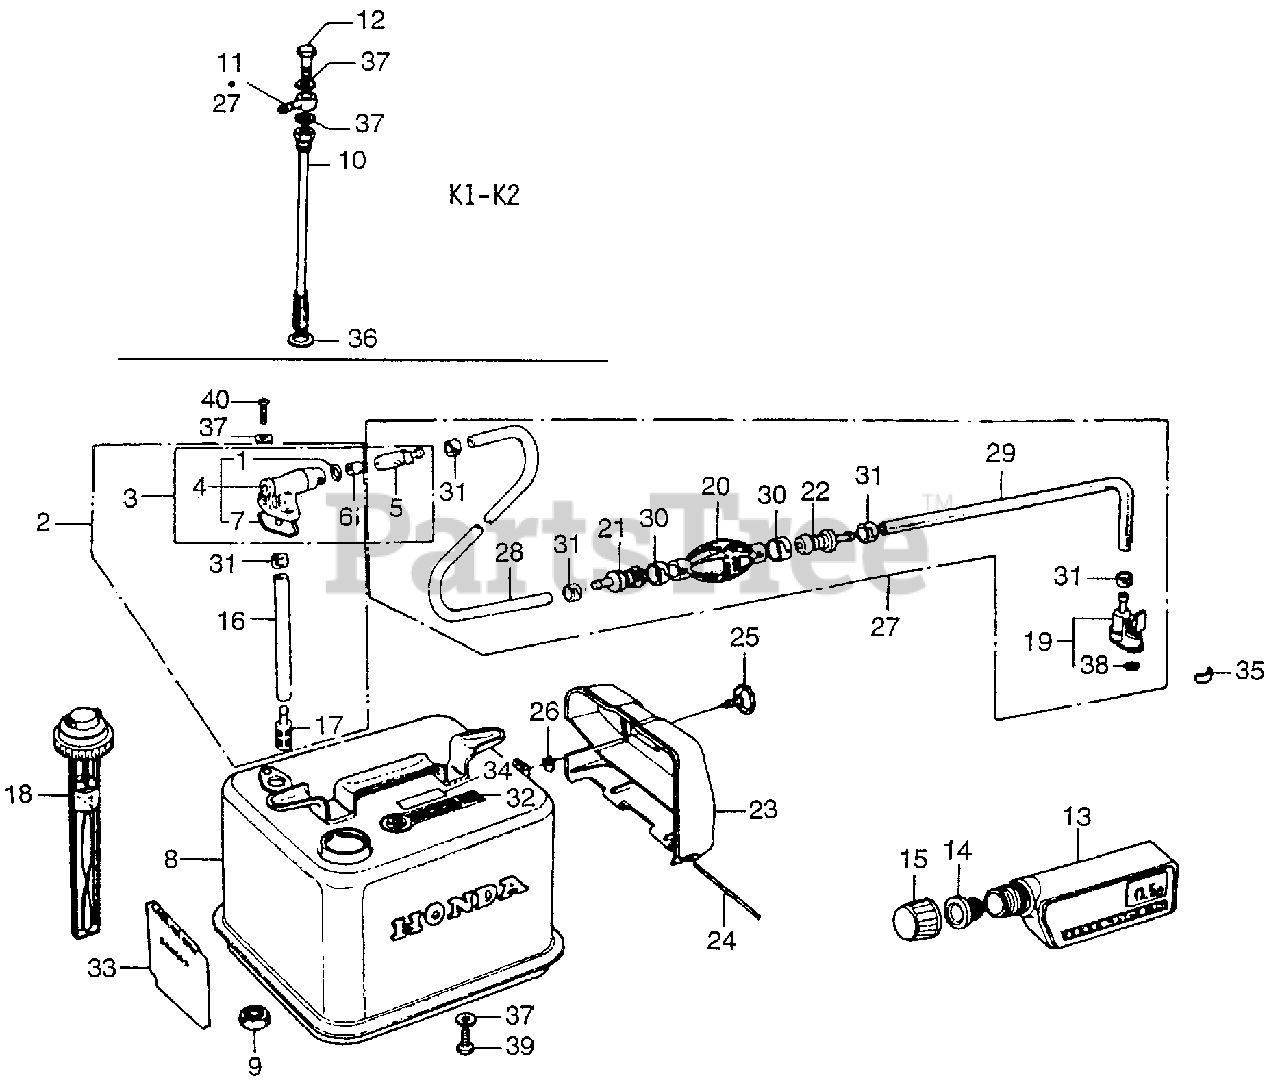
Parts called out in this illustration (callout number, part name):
8	TANK, FUEL *A5* (VOLVO ORANGE)
9	RUBBER, HOLDER
10	PIPE (INNER) (NOT AVAILABLE)
11	JOINT, TUBE
12	BOLT, TUBE JOINT
13	TANK, OIL
14	CAP, SUB-TANK (INNER)
15	CAP, SUB-TANK
18	CAP, FUEL FILLER (NOT AVAILABLE)
19	CONNECTOR, FUEL *NH1* (BLACK)
20	BULB, PRIMER
21	VALVE, IN.
22	VALVE, OUTLET
24	BAR (3X150) (NOT AVAILABLE)
25	LATCH, TOOL BOX
26	STOPPER, LATCH
27	TUBE ASSY., FUEL
28	TUBE, FUEL LONG
29	TUBE, FUEL SHORT
30	BAND, TUBE CLIP (20MM)
31	BAND, TUBE CLIP (11MM)
32	MARK, TANK CAUTION (NOT AVAILABLE)
33	LABEL B, TANK CAUTION
35	MARK, FUEL CONNECTOR (NOT AVAILABLE)
36	WASHER, PIPE (INNER)
37	GASKET, FIBER (6MM)
37	WASHER, JOINT TUBE
38	O-RING (5.5X3)
39	BOLT, HEX. (6X12)
